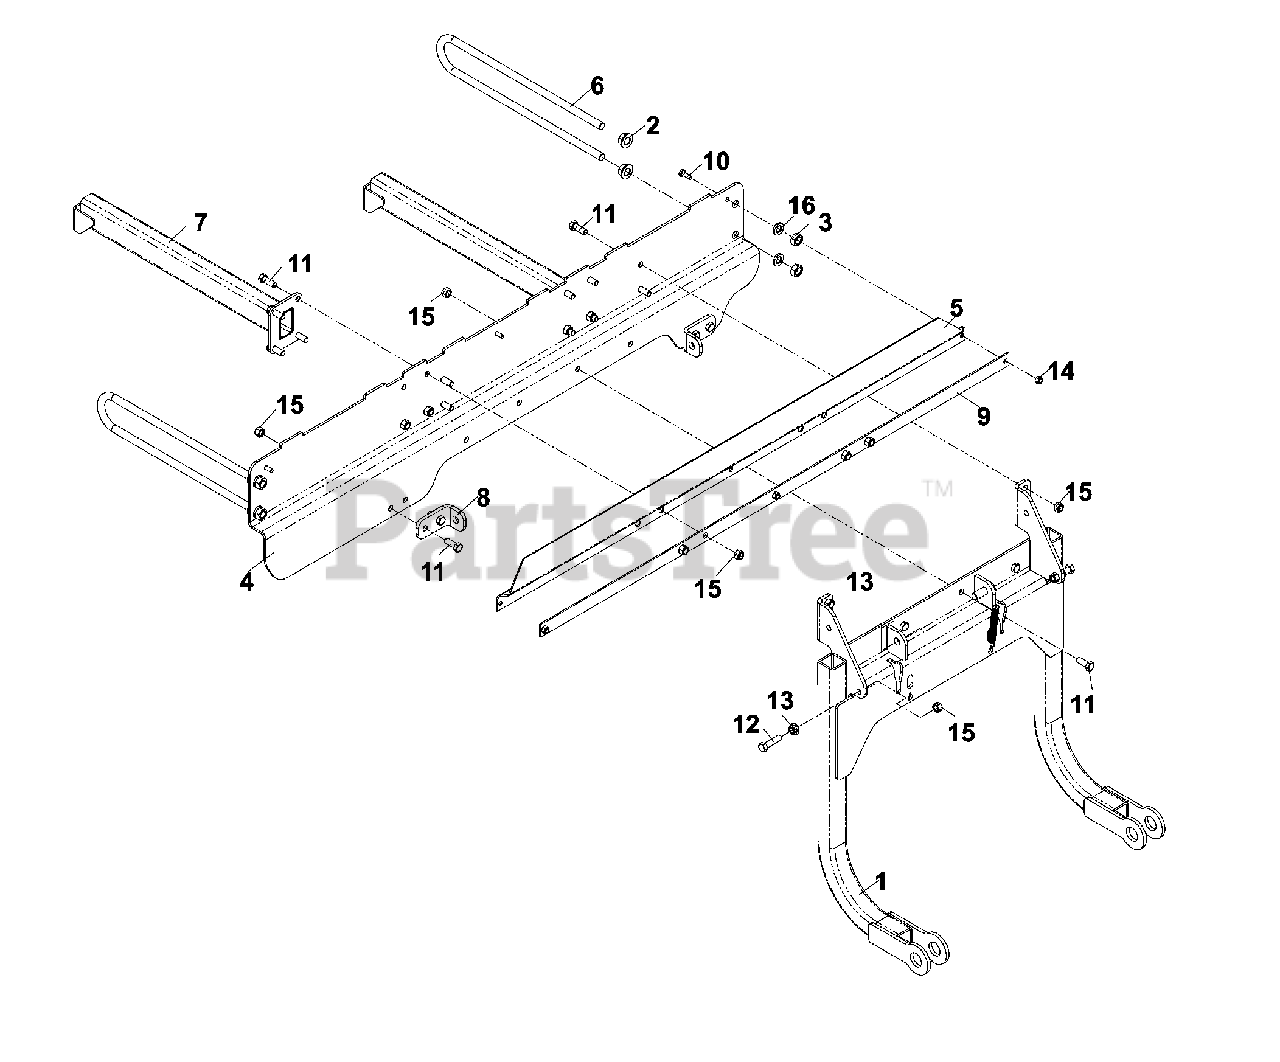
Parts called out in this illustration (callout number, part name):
1	HITCH WELDMENT
2	NUT 1/2-13 HEX
3	NUT 1/2 HEX JAM
4	MOUNT Z BRACE
5	SEAL, RUBBER
6	SUPPORT, OUTER
7	SUPPORT ARM WELDMENT
8	BRACKET, SUPPORT
9	SEAL STRAP
10	HCS 1/4C X 3/4 HCS
11	HCS 3/8C X 1
12	HCS 3/8C X 1 1/2
13	NUT 3/8C WHIZ
14	NUT 1/4-20 NYLOC
15	NUT 3/8-16 NYLOC
16	WASHER 1/2" SPLIT LOCK
